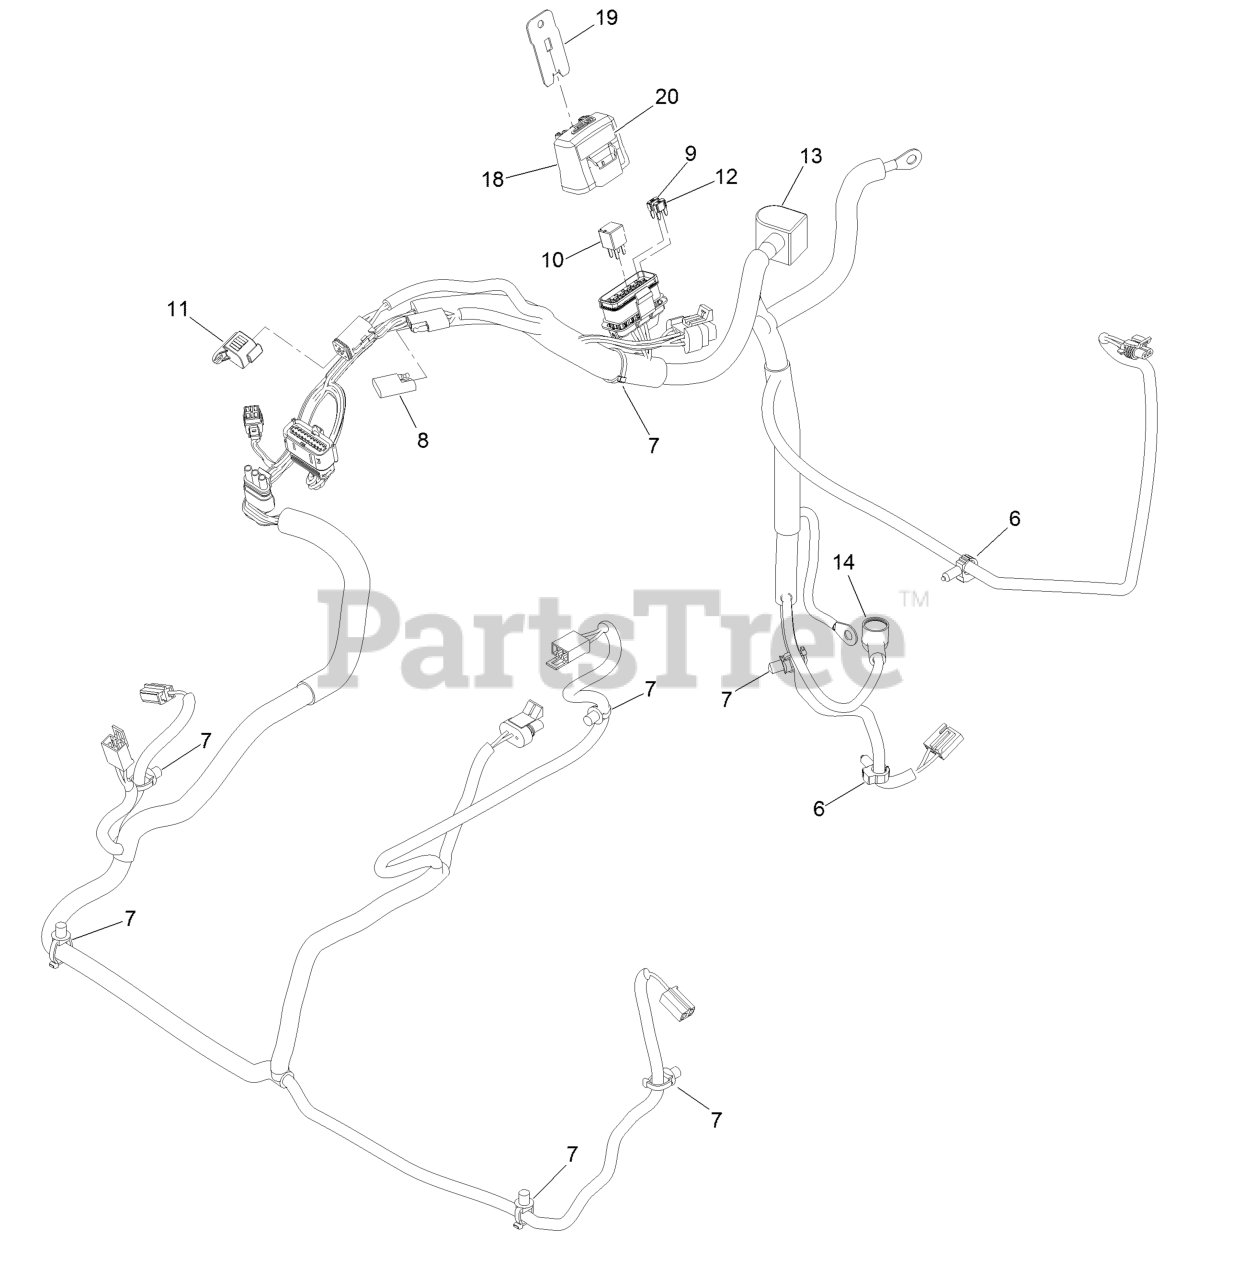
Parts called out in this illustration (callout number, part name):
6	Clip-Harness
7	Clip-Tie
8	Cap-Plug
9	Fuse-Mini Blade, 20 Amp
10	Relay-Micro
11	Cap-Plug, 6 Way
12	Fuse-Mini Blade, 15 Amp
13	Insulator-Battery
14	Insulator-Solenoid
18	Cover-Block, Fuse
19	Clip-Mounting
20	Decal-Fuse
